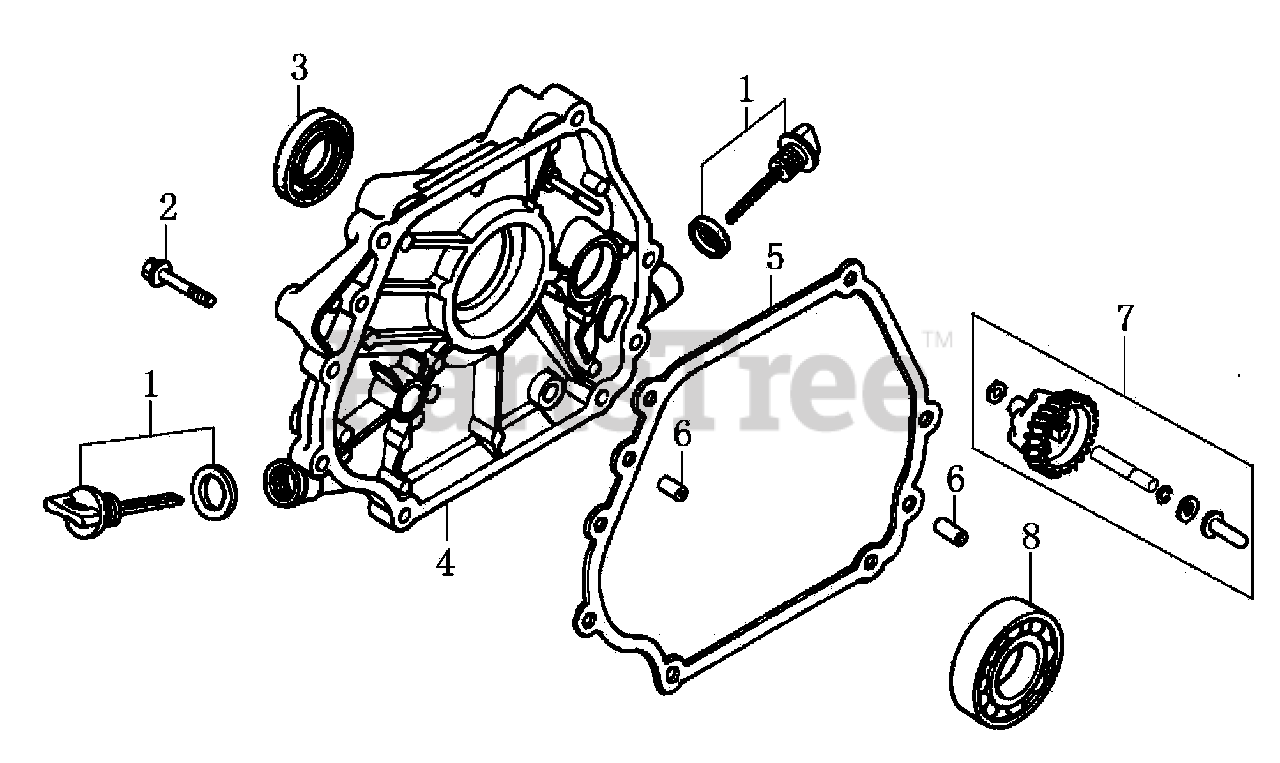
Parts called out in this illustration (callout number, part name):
1	CAP ASSY., DIP STICK/WASHER
2	BOLT, FLANGE 8X35
3	OIL SEAL 30X46X8
4	CRANKCASE COVER
5	GASKET, CRANKCASE COVER
6	DOWEL PIN 8X12
7	GOVERNOR KIT
8	BALL BEARING 6206
